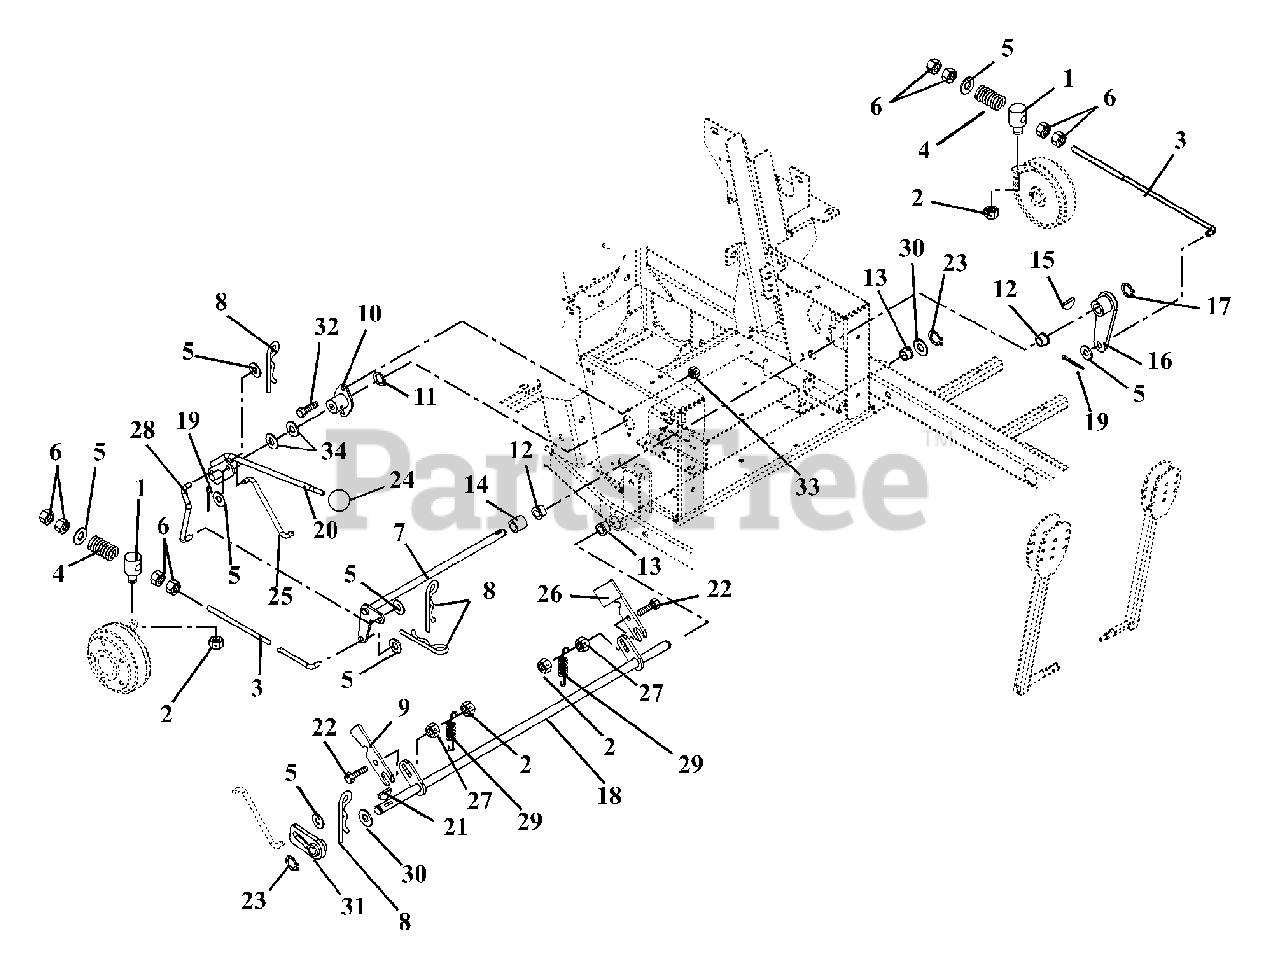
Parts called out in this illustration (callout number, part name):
1	PIN, PIVOT/TRUNNION
2	@NUT-LK-CTR .31-18 YWZC
3	PTO LINK ROD, PRO-150
4	SG-COMP .142 X .710 X 1.75
5	@WSHR-FL-STL.406X.812X.065 YWZ
6	@NUT-HEX .38-16 YWZC
7	WMT, BRAKE CROSS SHAFT
8	PIN-HAIR, ENDRIES #25 YWZC
9	SLIDE, INTERLOCKING BRAKE
10	BUSHING, FLANGED
11	RG-RTNG-EXT .625X.050
12	BSHG-FLG .762X1.0X.580X1.48 NY
13	BSHG-FLG .515X.750X.745X1.00NY
14	BSHG-SLV .750X1.000X.750
15	KEY-WDRF .19X.75 HRD #9
16	WMT, BRAKE ARM
17	RG-RTNG-EXT .689X.078
18	WMT, MECHANICAL BRAKE
19	@PIN-CTR .09X.75 EXTPRSQCT YWZ
20	WMT, BRAKE ACTUATING LEVER
21	KEY-WDRF .13X.63 HRD#5
22	@BLT-RDHDSQNK .31-18X1.25 G5YZ
23	RG-RTNG-EXT .500X.050 (SNAP)
24	KNOB-STEERING LOCK
25	LINKAGE, BRAKE ACTUATING
26	INTERLOCK, SAFETY SWITCH
27	@NUT-LK-TOP-FLG .31-18 YWZC
28	LINKAGE, BRAKE ACTUATING
29	SG-TENS .063X.44X1.56
30	WSHR-FL-STL .505X1.00X.062YWZC
31	WMT, PARKING BRAKE HUB
32	@BLT-HEX .31-18X.75 GR5 YWZC
33	@NUT-LK-TOP-FLG .31-18 YWZC
34	WSHR-FL-STL .630X1.250X.062 YZ
